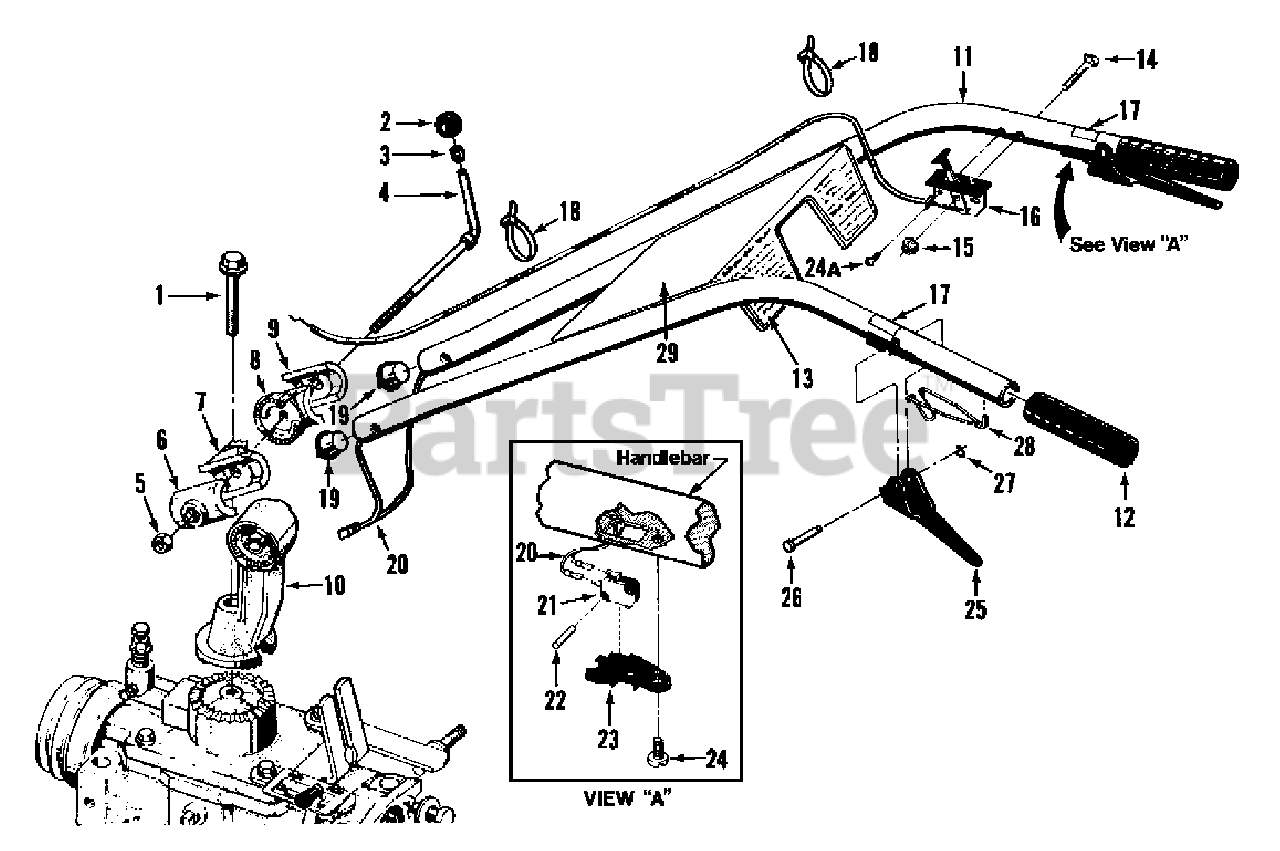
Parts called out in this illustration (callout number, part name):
1	Bolt-Hex hd., flanged self-locking Grade 5, 1/2-13 x 3-1/2"
2	Knob-handlebar height adjustment
3	Ring-retaining (tolerance ring)
4	Stud-handlebar height adjustment
5	Nut-hex, 1/2"-13
6	Clamp-left, handlebar height adjustment
7	Ratchet-left, handlebar height adjustment
8	Ratchet-right, handlebar height adjustment
9	Clamp-right, handlebar height adjustment
10	Base-handlebar mounting
12	Grip-handlebars
13	Decal-Control panel
14	Bolt-curved hd, GR5, 1/4-20 x 2"
15	Nut-hex, flanged self-locking, whiz lock, 1/4"-20
16	Throttle Control & Cable, 66"
17	Decal-Forward Interlock Lever
18	Tie-plastic
19	Plug-wire harness retainer
20	Handlebar Wire Harness Assy- forward interlock system
21	Handlebar Switch-forward interlock system
22	Lock Pin-handlebar switch
23	Switch Housing-handlebar switch
24	Screw-pan head, 10-24 x 1/2", thread-forming
24A	Screw-phillips head, 10-32 x 1/2", thread-forming
26	Pivot Pin-forward interlock lever
27	Retaining Ring-klip ring-forward interlock lever
28	Return Spring-fwd interlock lever
29	Label - Troy-Bilt Horse
